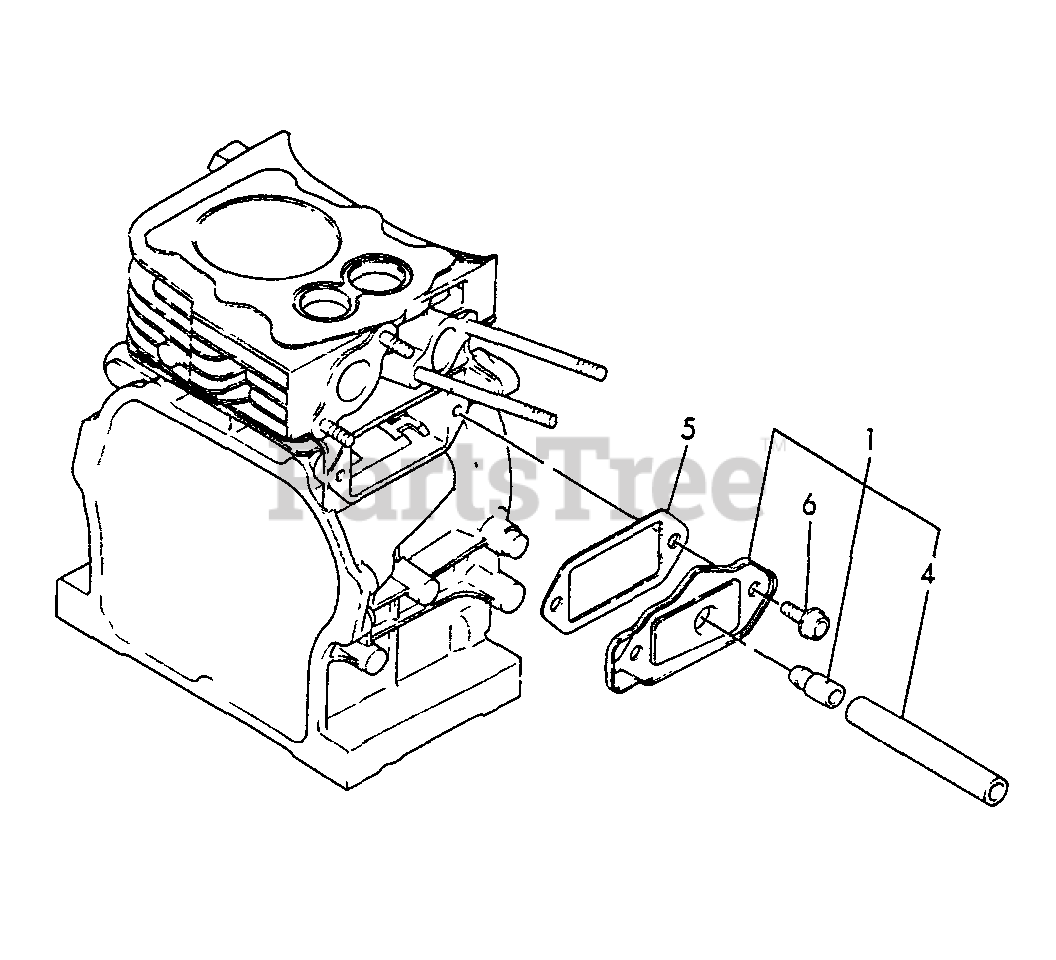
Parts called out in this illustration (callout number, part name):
1	BREATHER ASSY
4	PIPE, BREATHER
5	GASKET
6	BOLT - 6×8 -- PLATED
